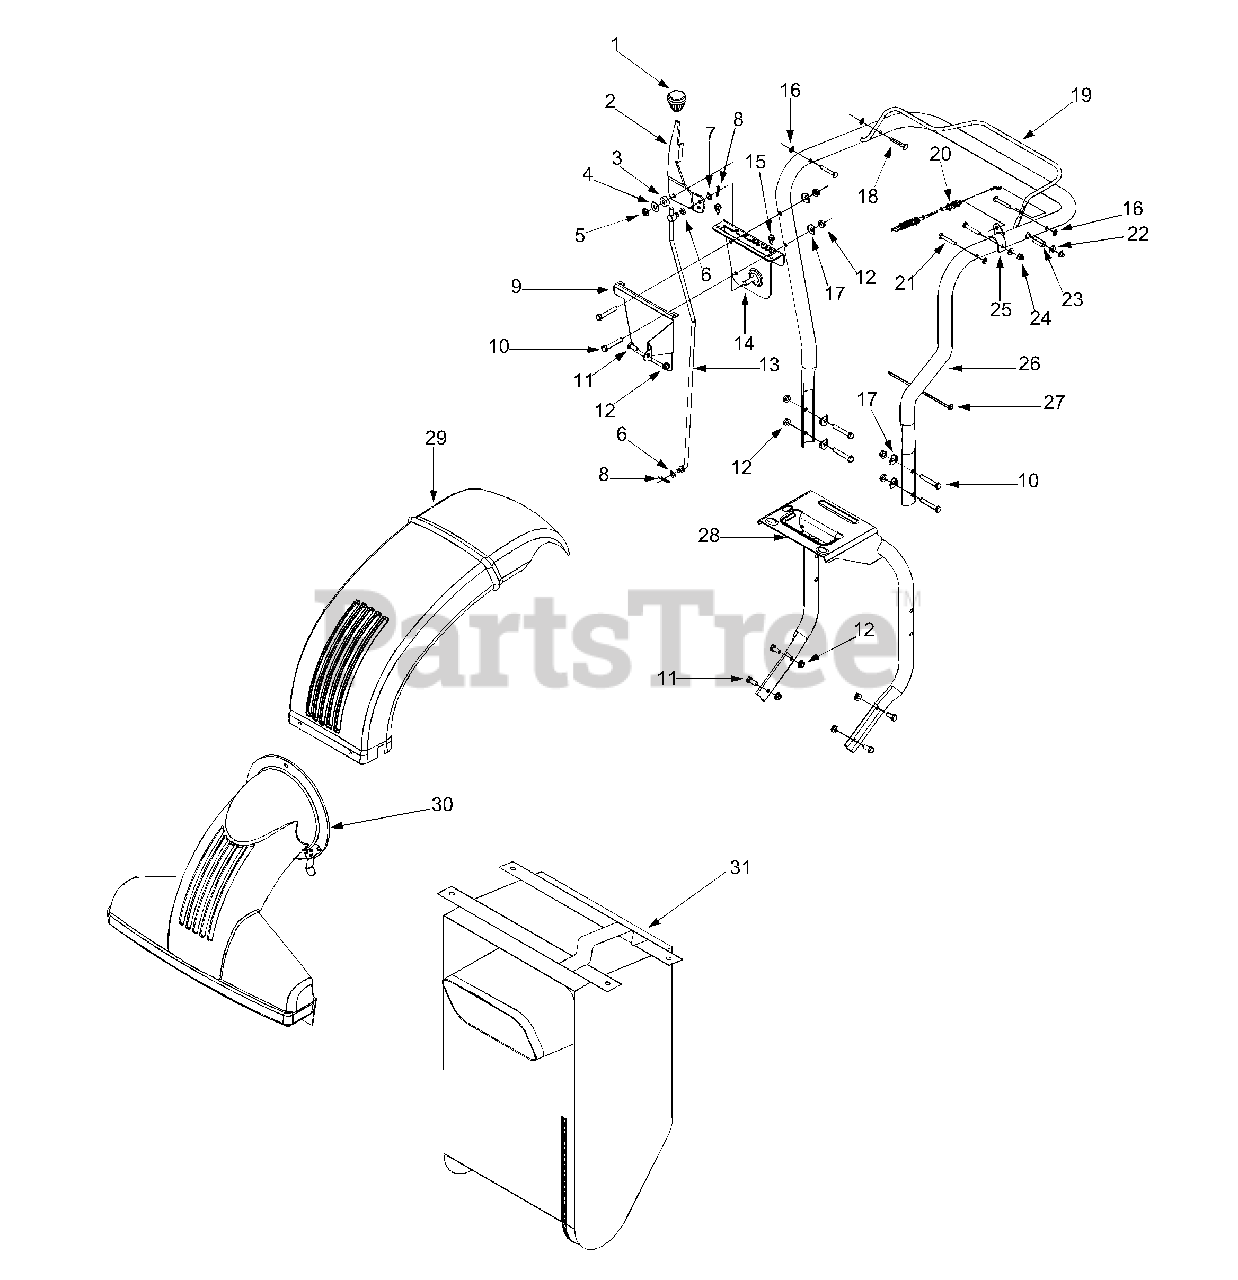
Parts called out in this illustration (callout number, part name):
1	Shift Knob
4	Flat Washer
5	Lock Nut 3/8-24
6	Spring Washer
7	Flat Washer .375 ID x .620 OD
8	Cotter Pin
11	Hex Cap Screw 5/16-18 x .75
12	Flange Lock Nut 5/16-18
13	Shift Rod
16	Push Nut .250
17	Shoulder Washer .320 ID x .93 OD
18	Pin .250 x 1.75
21	Hex Cap Screw 1/4-20 x 1.75
22	Flat Washer 5/16
23	Spacer .345 ID x .51 OD
24	Lock Nut 1/4-20
30	Nozzle Assembly
31	Vacuum Bag
